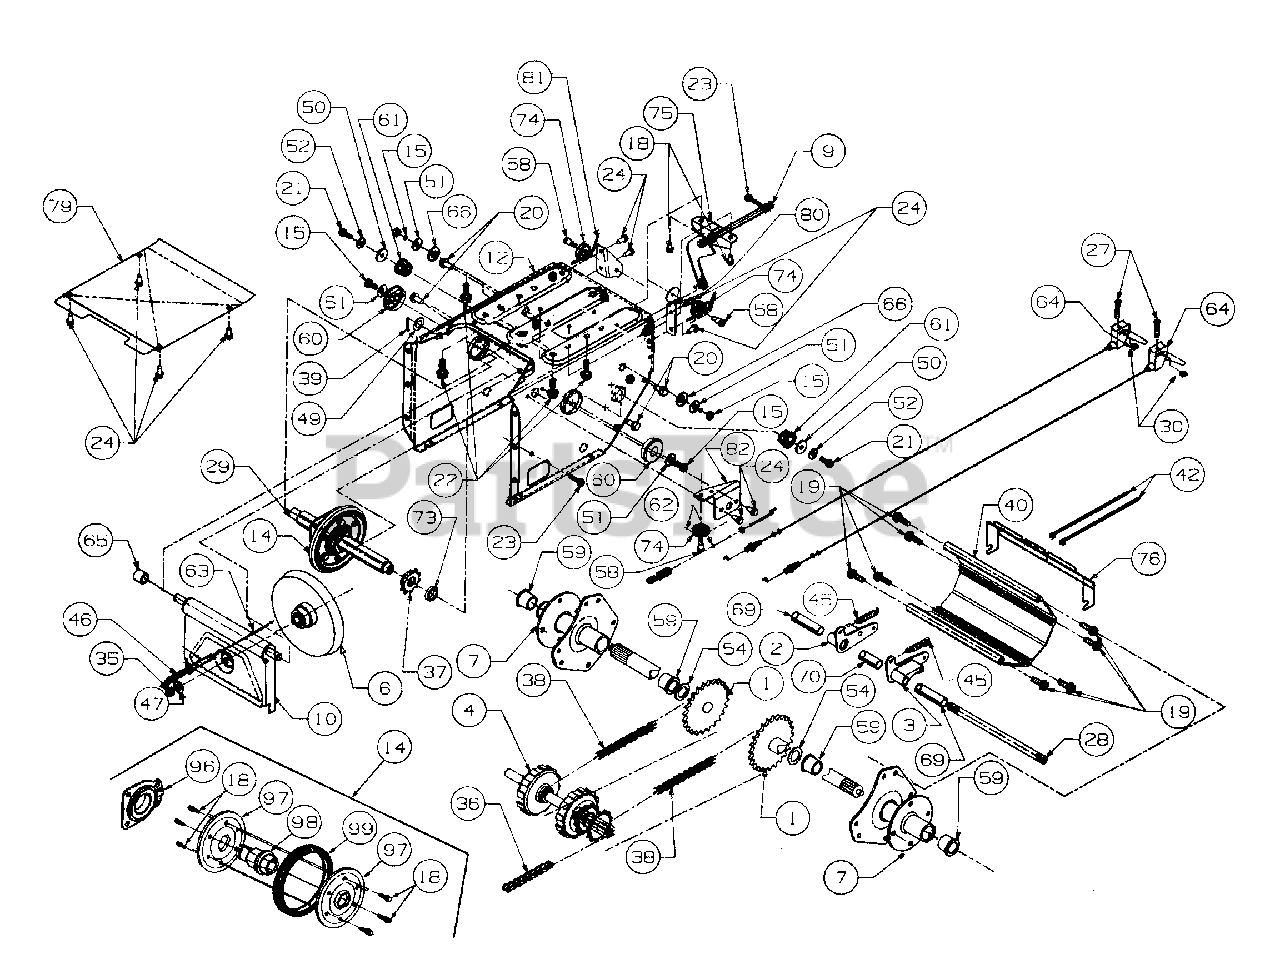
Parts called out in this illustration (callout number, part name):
1	Axle Assembly
2	Dog Assembly, RH
3	Dog Assembly, LH
4	Steering Shaft Ass'y, Track
6	Disc Assembly, Friction
14	Friction Wheel Assembly
15	Screw, Hex Cap, 5/16-18 x .75
18	Screw, Hex Wash Hd Tapp 1/4-20 x .5
19	Screw, Hex Wash Hd Tapp 5/16-18 x 1.0
20	Screw, Hex Wash Hd Tapp 5/16-16 x .62
21	Screw, Hex Wash Hd Tapp 1/4-20 x .75
22	Screw, Hex Wash Hd Tapp 3/8-16 x 1.0
23	Screw, Hex Wash Hd Tapp 1/4-20 x 1.0
24	Screw, Hex Wash Hd Tapp 1/4-14 x .625
27	Screw, Oval Hd Cntrsnk
28	Actuator Shaft
29	Shaft, Hex Drive
30	Nut, Flat Weld, #10-24
35	Nut. Hex Jam
36	Chain, #41 x 30 Lnks
37	Sprocket, 10T
38	Chain, #420 x 32 Links Endless
39	Pin, Cotter, .125 x 1.25
40	Housing, Track
42	Cable Tie
45	Spring, Extension
46	Spring, Extension
47	Washer, Bell, .401 x .87 x .063
49	Washer, Flat, .563 x .93 x .05
50	Washer, Flat, 1/4 x .93 x .12
51	Washer, Bell, .345 x .88 x .06
52	Washer, Bell, .265 x .75 x .062
54	Washer, Flat, .793 x 1.24 x .06
58	Shoulder Screw
59	Bearing, Flange, .75 ID x 1.0 OD
60	Bearing, Ball
61	Bearing, Hex Flange
62	Cable, Auger Clutch
63	Cable, Drive Clutch
64	Cable, Track Steering w/Trigger
65	Spacer, .508 x .75 x .68
66	Shoulder Spacer
69	Spacer, Split .514 x .63 x 2.44
70	Spacer, Split .514 x .63 x 1.59
73	Spacer, .675 x 1.0 x .23
74	Cable Roller
97	Friction Plate
98	Friction Wheel Hub
99	Friction Wheel Rubber
